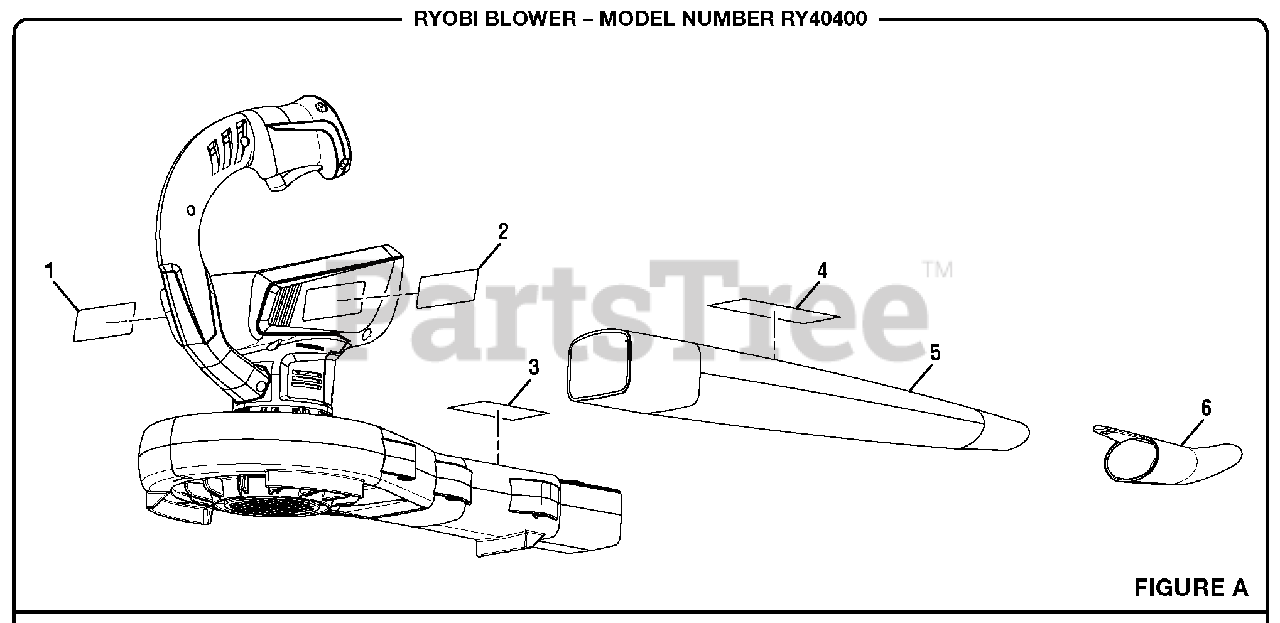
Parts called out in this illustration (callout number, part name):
1	Logo Label
2	Data Label
3	Warnings Icon Label
4	Tube Logo Label
5	Blower Tube
6	High Speed Nozzle
